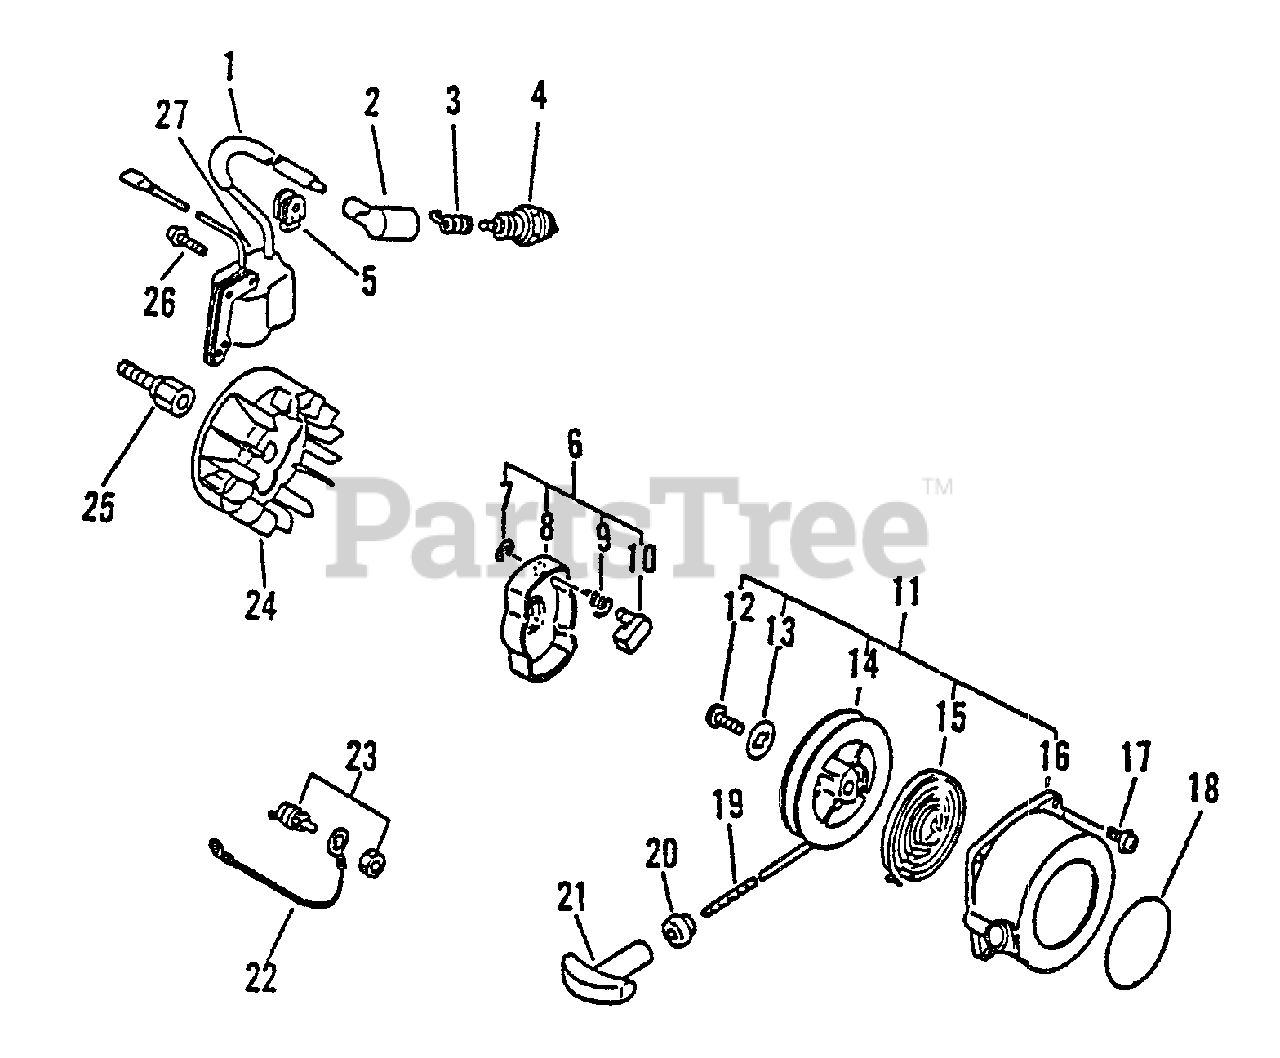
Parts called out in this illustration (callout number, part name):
2	CAP, SPARK PLUG
3	TERMINAL, SPARK PLUG CAP
4	SPARK PLUG -- BPM-7A
6	STARTER PAWL ASSY
7	RING, RETAINING - 4
8	CATCHER, PAWL
9	SPRING, RETURN
10	PAWL, STARTER
11	STARTER ASSY
13	WASHER
14	REEL, ROPE
15	SPRING, REWIND
16	CASE, STARTER
17	SCREW - 4X18
18	LABEL - LESCO
19	ROPE, STARTER - 3X890
20	GUIDE, ROPE
21	GRIP, STARTER
22	LEAD - GROUND
23	IGNITION SWITCH ASSY
24	FLYWHEEL
25	HUB, FAN
26	SCREW - 4X22
27	COIL, IGNITION
